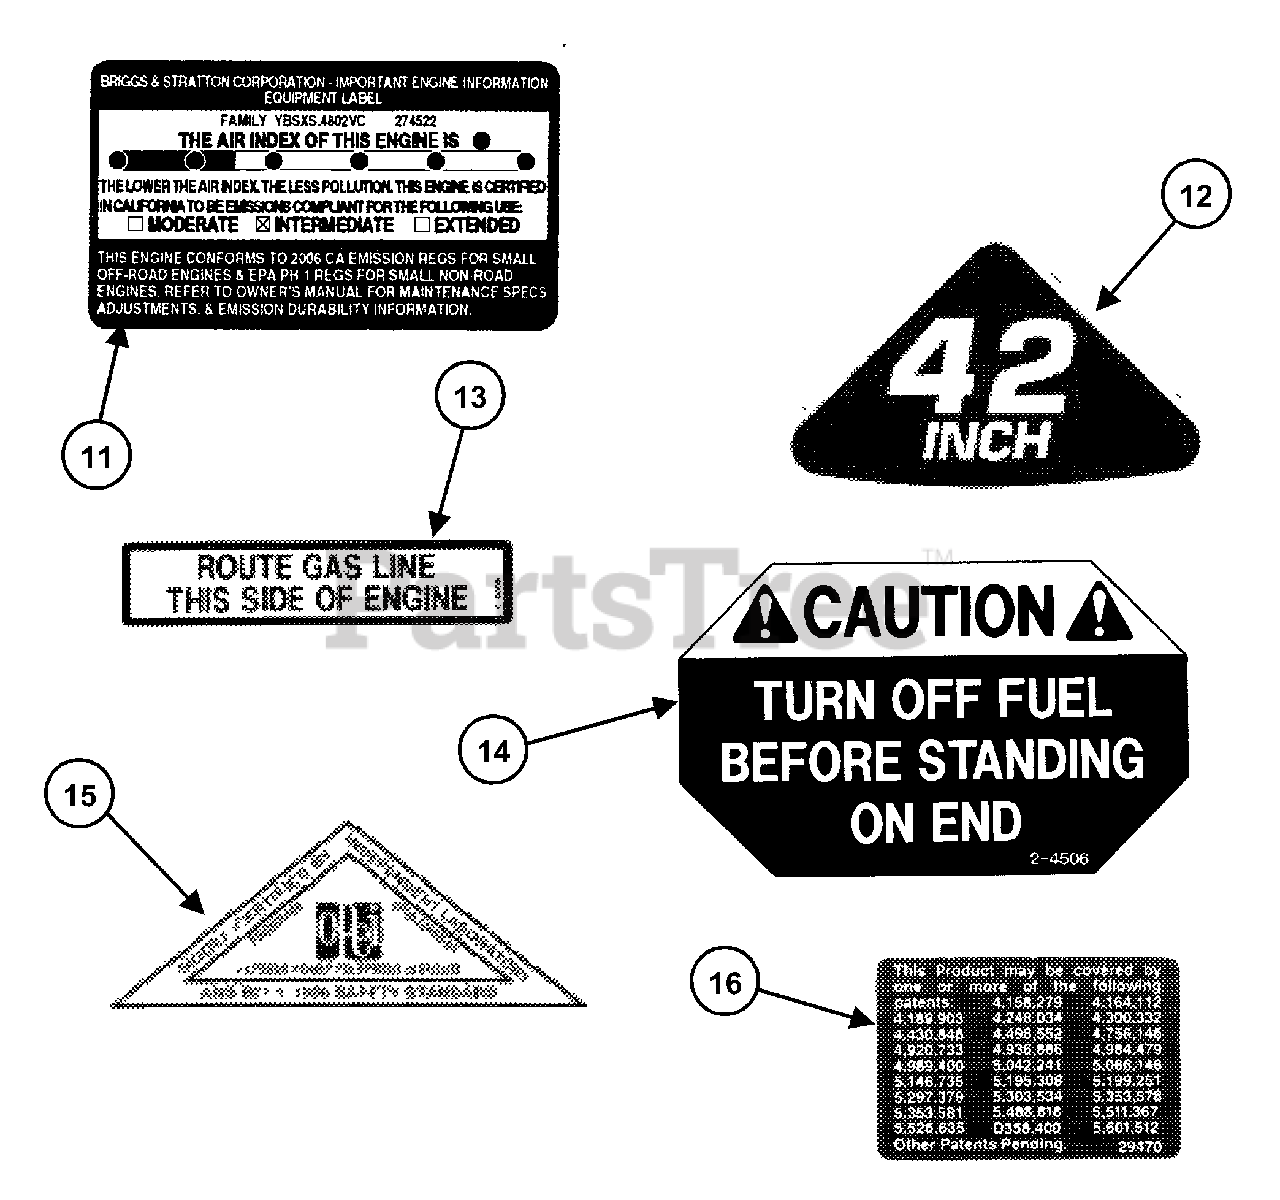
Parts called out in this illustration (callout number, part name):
11	DECAL, B&S Air Index/Emission Label
12	DECAL, 42 Inch
13	DECAL, Fuel Routing
14	DECAL, Fuel Shut-Off
15	DECAL, OPEI Ride On
16	DECAL, Patent Numbers
